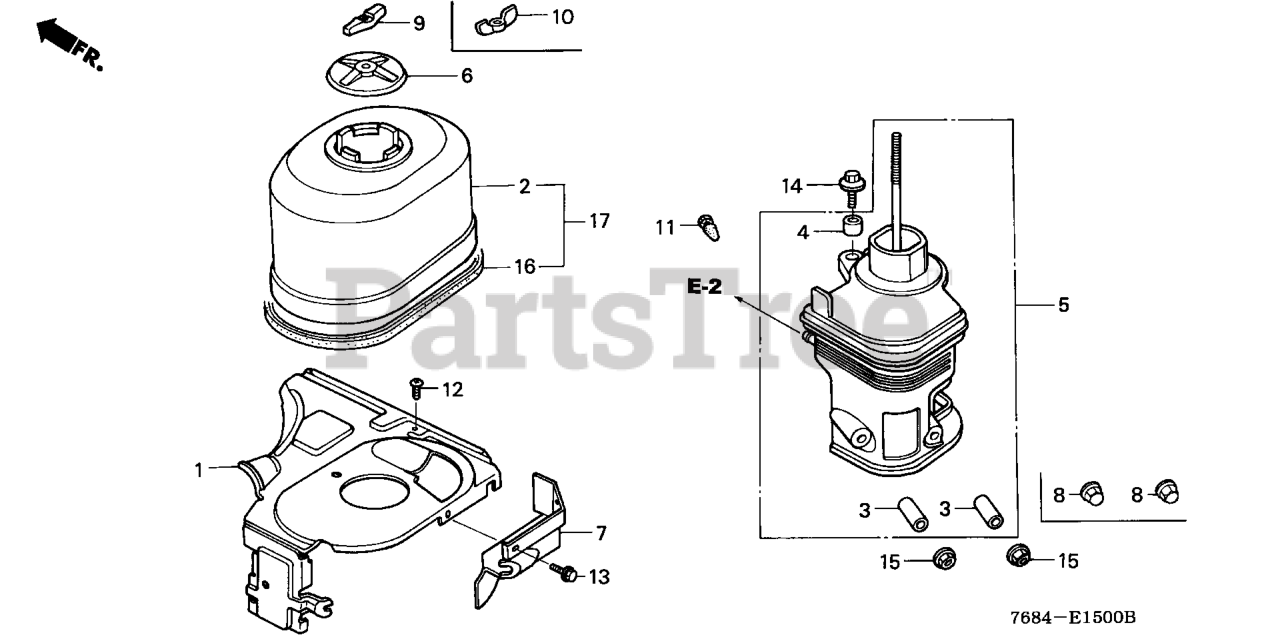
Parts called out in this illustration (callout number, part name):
1	COVER, CONTROL
2	COVER, AIR CLEANER (SEMI-DRY)
3	COLLAR, AIR CLEANER
4	COLLAR B, AIR CLEANER
5	ELBOW, AIR CLEANER
6	CAP, AIR CLEANER
7	COVER, AIR IN.
10	WINGNUT, TOOL BOX SETTING
11	PLUG, CONE TYPE
12	SCREW, PAN (6X8) (SOURCE: VINTAGE PARTS INC.)
13	BOLT, FLANGE (6X8)
14	BOLT, FLANGE (6X35)
15	NUT, FLANGE (6MM)
